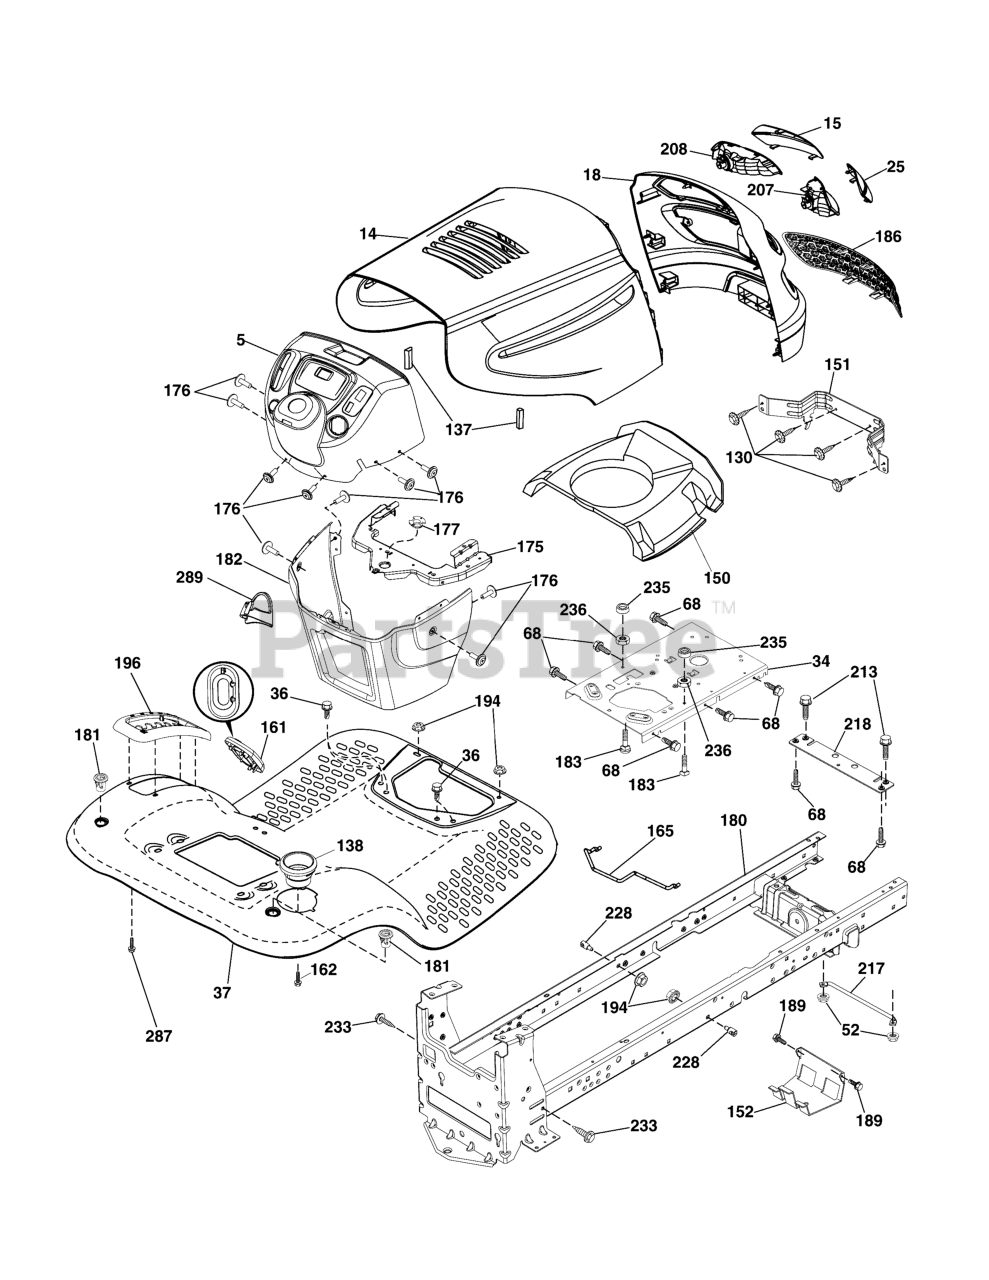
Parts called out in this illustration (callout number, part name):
5	Dash
14	Hood
15	Lens Grille LH
18	Grille Asm
25	Lens Grille RH
34	Plate Engine
36	Screw 5/16-18 x 3/4
37	Fender
52	Nut Lock 5/16-18
68	Screw Thdrol 5/16-18 x 1/2
130	Screw #10 x 0.750
137	Bumper Hood
138	Cupholder
150	Duct Heat Hood
151	Bracket Pivot
152	Shield Browning/Debris
161	Window Fuel
162	Screw Hex Wsh Hi-Lo 1/4 x 1/2
165	Support Tank Rear
175	Crossmember
176	Screw 10-24 x 5/8 Wshd Qdrx
177	Bushing Steering
180	Chassis
181	Bushing Mtg. Fender Crgo.
182	Dash Lower
183	Bolt Fin Hex 5/16-18 x 1-1/4
186	Insert Grille
189	Screw 5/16-18 x 3/4
194	Nut Lock Hex Flange 5/16-18
196	Console Asm. Deck Lift
207	Bezel Grille RH
208	Bezel Grille LH
213	Bolt 5/16-18 unc x 3/4
217	Rod Pivot Hood
218	Hood Stop
228	Stud Fastener
233	Bolt Shoulder
235	Spacer Fender
236	Nut Center Lock 5/16-18
287	1/4-20 x 3/8
289	Phone Holder
